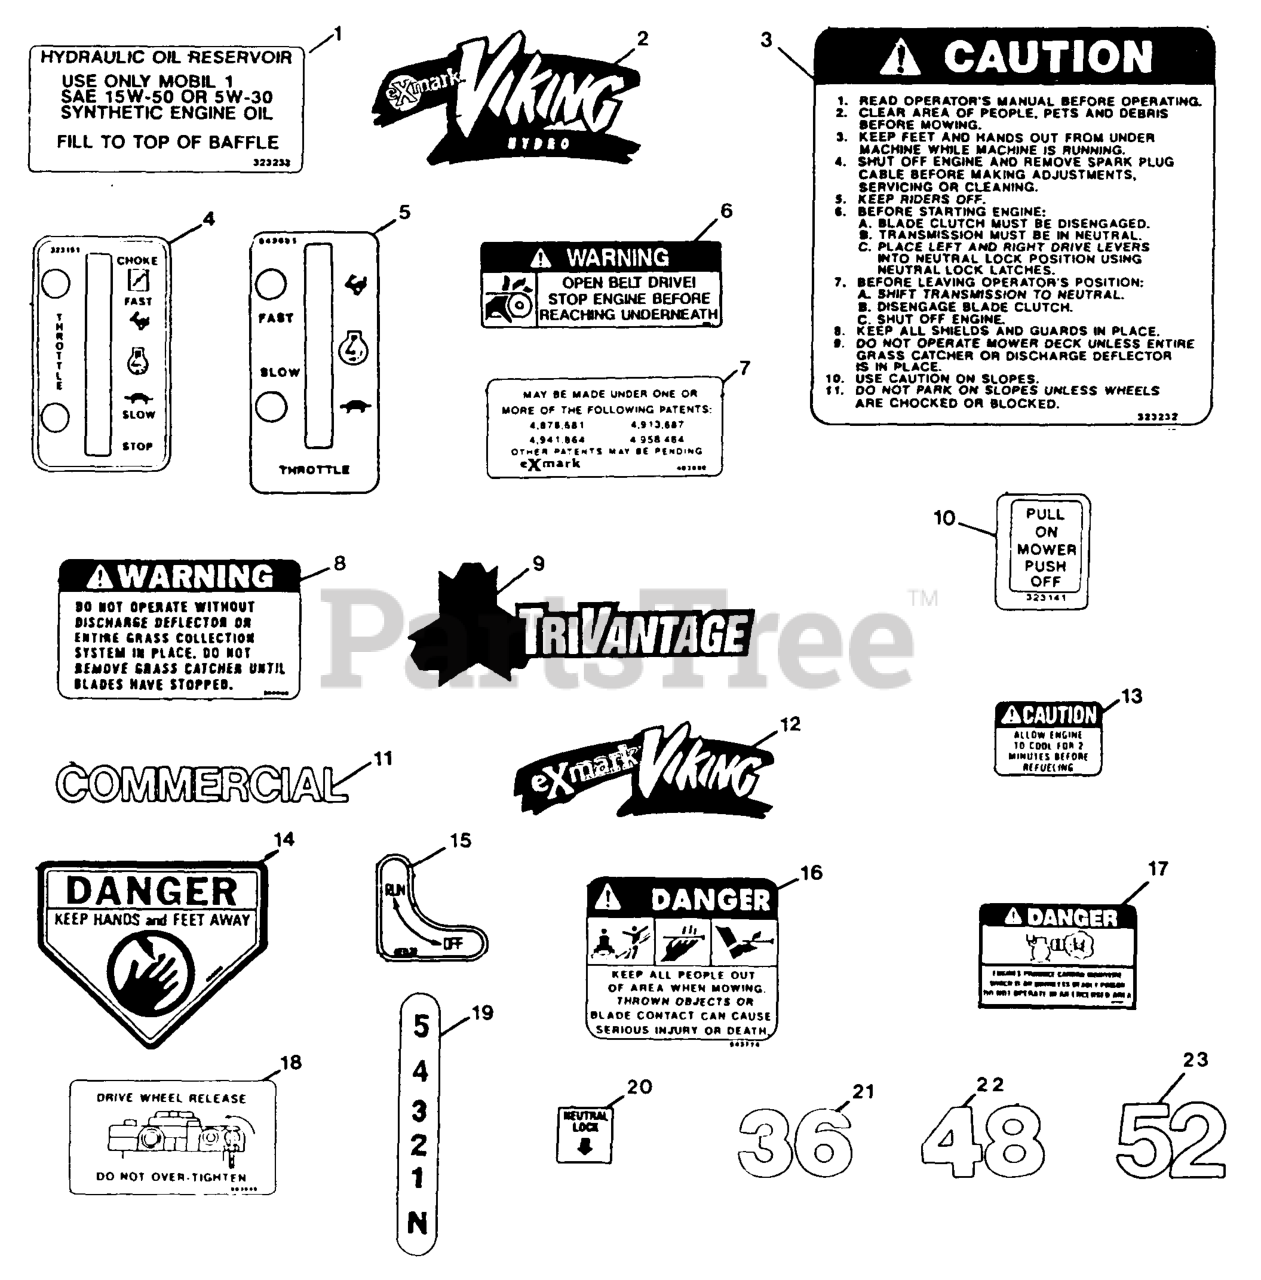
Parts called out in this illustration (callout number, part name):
3	DECAL,INSTRUCTIONAL
6	DECAL,BELT DRIVE
8	DECAL-WARNING, DISCHARGE
14	DECAL-DANGER
16	DECAL-DANGER
18	DECAL,DRIVE RELEASE
19	DECAL - SHIFTER
20	DECAL,NEUTRAL LOCK
